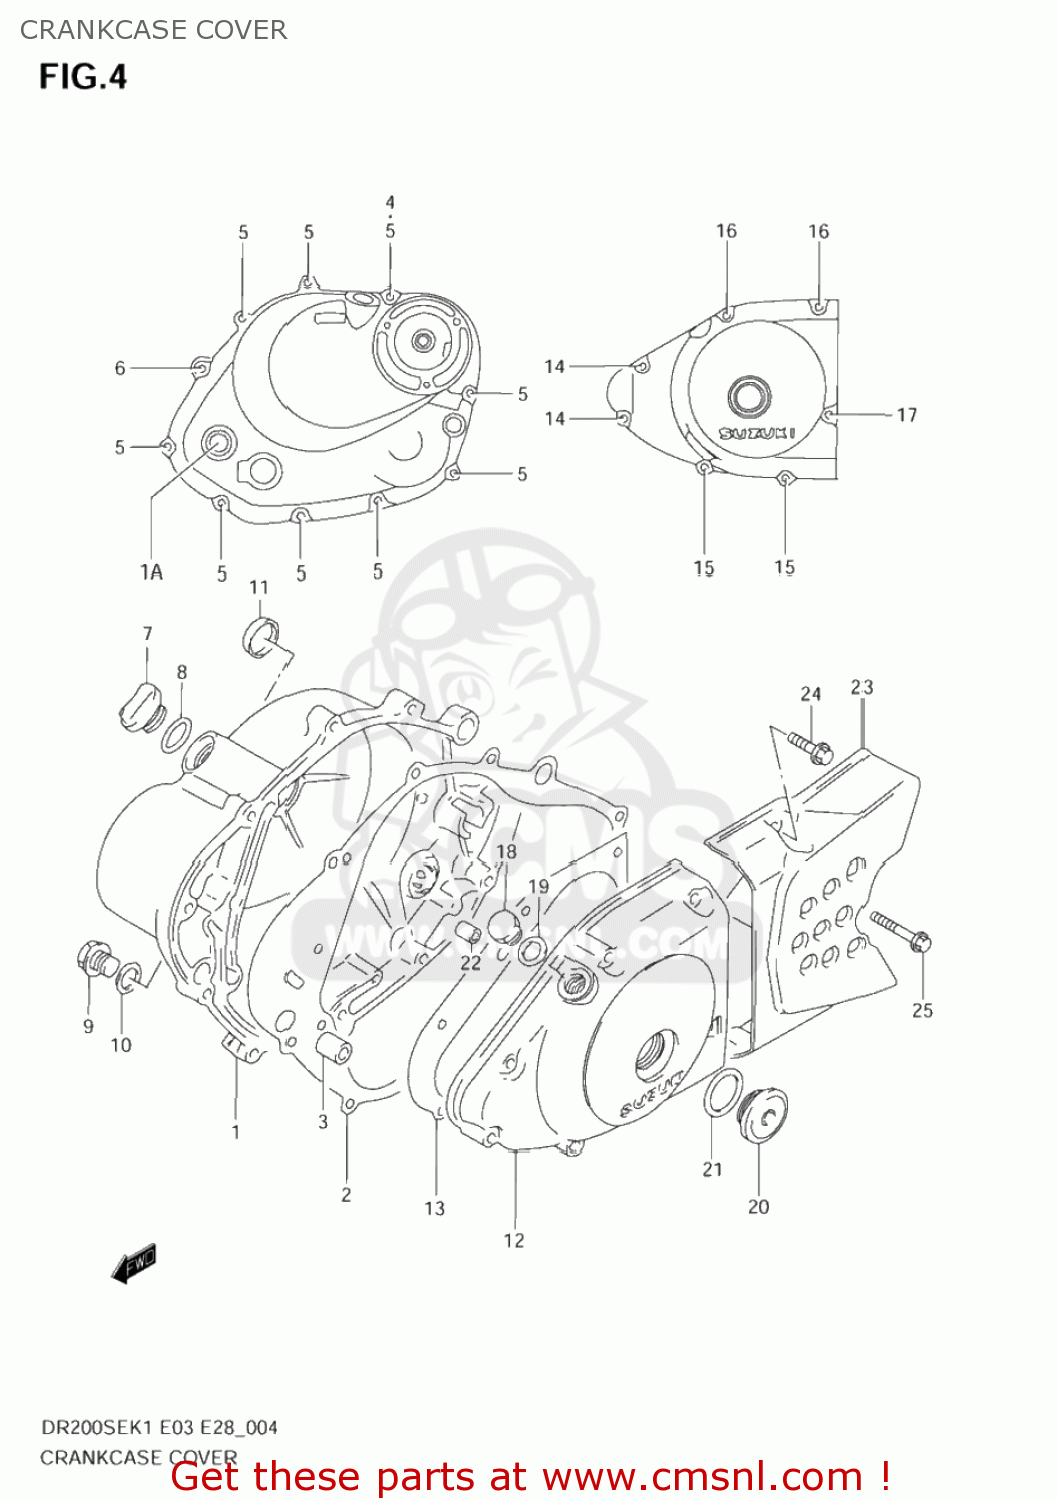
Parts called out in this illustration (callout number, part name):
1	COVER,CLUTCH
1A	LENS,OIL LEVEL CHECK
2	GASKET,CLUTCH COVER (NAS)
3	PIN
4	GASKET(5.8X13X1.2) (NAS)
5	BOLT,G/S SWITC
6	BOLT
7	PLUG
8	O RING(D:3.1,ID:16.8)
9	PLUG(14X12)
10	GASKET(13.8X18.8X4.8) (NAS)
11	PLUG,CLUTCH COVER KICK
12	COVER,MAGNETO
13	GASKET,MAGNETO COVER (NAS)
14	BOLT,G/S SWITC
15	BOLT
16	BOLT
17	BOLT
18	PLUG,12X9
19	GASKET(12.1X16.2X3.7) (NAS)
20	PLUG(26X9)
21	O RING(D:3.1,ID:22.7)
22	PIN
23	COVER,ENGINE SPROCKET
24	SCREW
25	BOLT
